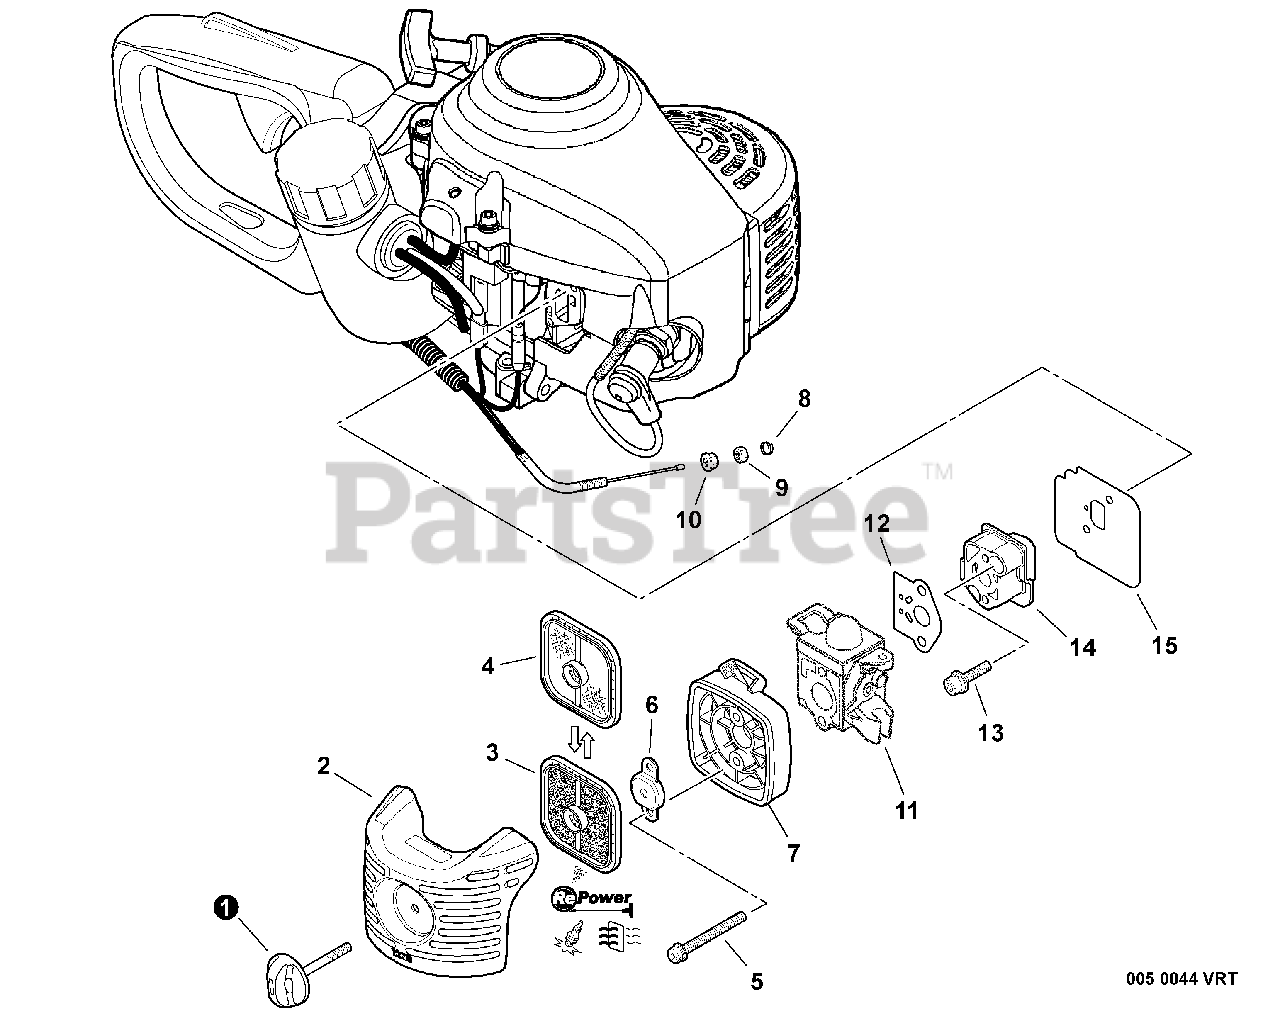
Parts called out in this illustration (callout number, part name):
1	THUMBSCREW
2	COVER, AIR FILTER
3	FILTER, AIR - DOUBLE LAYER
4	FILTER, AIR - SINGLE LAYER
5	SCREW - 5X65
6	PLATE, PREVENT
7	CASE, AIR FILTER
10	NUT - 6 -- FLANGE
11	CARBURETOR
12	GASKET, INTAKE
13	SCREW - 5X25
14	INSULATOR, INTAKE
15	SHIELD, INTAKE
TU	RePower TUNE-UP KIT
FF	RePower FILTER KIT
